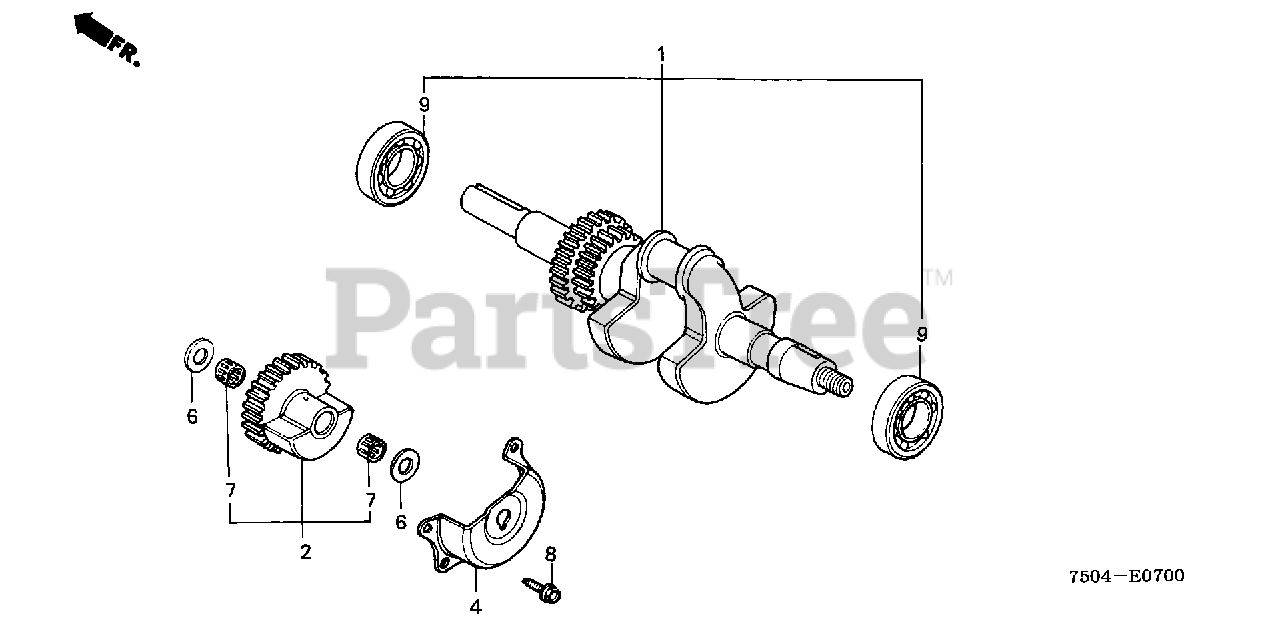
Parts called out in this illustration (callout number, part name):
1	CRANKSHAFT (S-TYPE)
2	WEIGHT, BALANCER
4	COVER, BALANCER
6	WASHER, THRUST (15MM)
7	BEARING, NEEDLE
8	BOLT, FLANGE (6X16)
9	BEARING, RADIAL BALL (6206)
